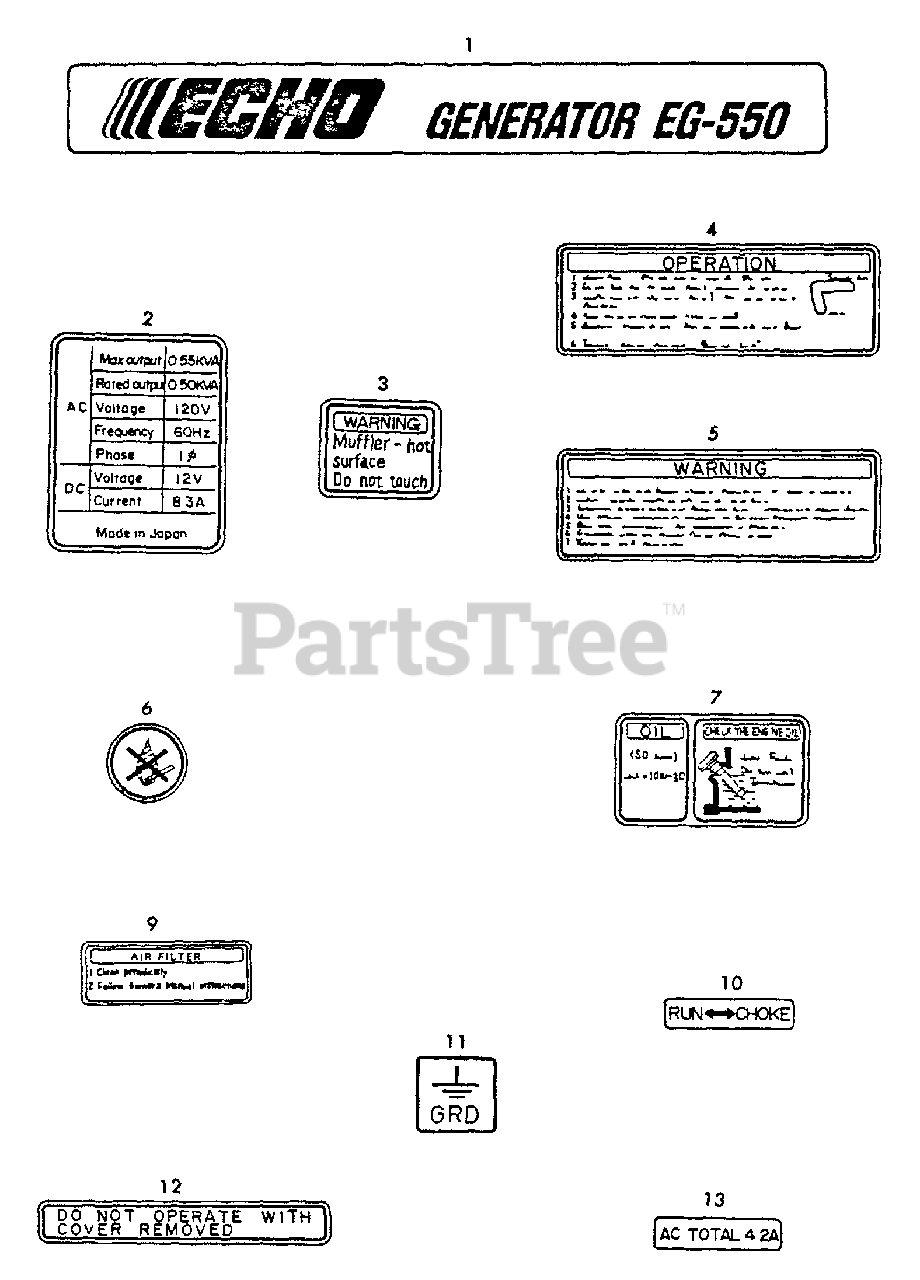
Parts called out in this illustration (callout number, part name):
1	LABEL - MODEL EG550
2	LABEL - GENERATOR
3	LABEL - CAUTION
4	LABEL - CAUTION -- OPERATION
5	LABEL - WARNING
6	LABEL - NON FIRE
7	LABEL - OIL
9	LABEL - AIR CLEANER
10	LABEL - CHOKE
11	LABEL - GROUND
12	LABEL - CAUTION
13	LABEL - AMPERE
